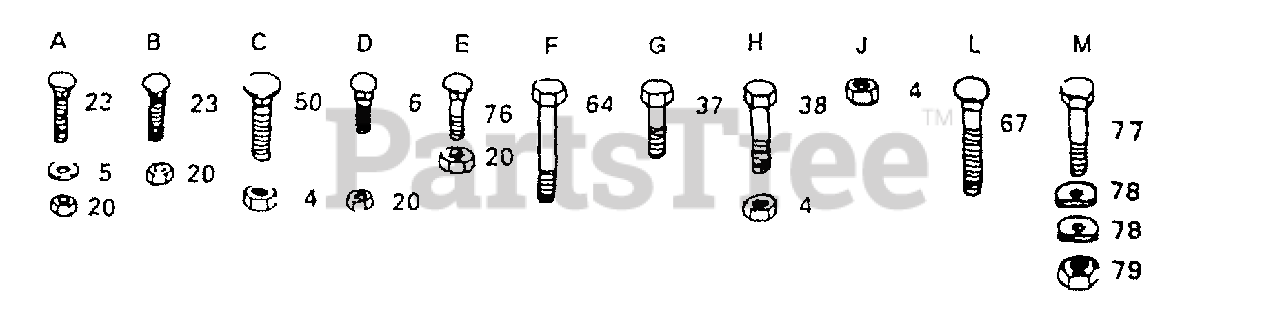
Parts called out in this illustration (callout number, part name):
4	Nut, Lock 3/8 - 16
5	Washer 11/32 x 3/4 x 1 6 Ga.
6	Bolt, Carr., 5/16-18 x 5/8
20	Nut, Lock 5/16 - 18
23	Bolt, Carriage 5/16 - 18 x 3/4
37	Screw, Hex Washer Hd. 3/8 -16 x 7/8
38	Screw, Hex Washer Hd. 3/8 -16 x 1-1/4
50	Bolt, Carriage 3/8 - 16 x 3/4
64	Bolt 3/8 -16 x 5 - 1/2
67	Bolt, Carriage 3/8 - 16 x 1 - 1/4
76	Bolt, Carriage 5/16 - 18 x 3/4
77	Bolt Hex 1/4 x 20 x 3/4
78	Washer, Special
79	Nut, Lock 1/4 - 20
